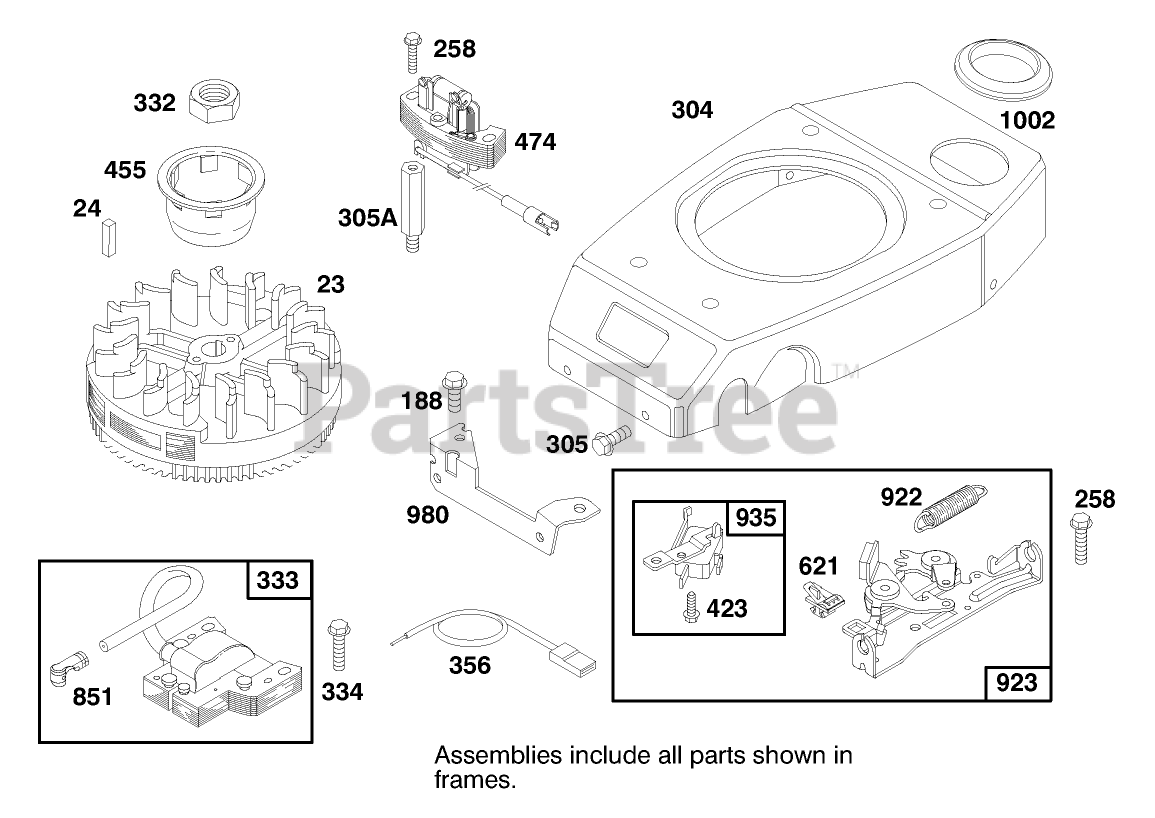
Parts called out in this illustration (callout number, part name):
23	FLYWHEEL - MAGNETO
24	KEY - FLYWHEEL
305	SCREW - HEX HEAD
332	NUT - HEXAGON
334	SCREW - SEM
356	WIRE - GROUND
455	CUP - STARTER
621	STOP SWITCH
980	BRACKET-BLOWER HSG
